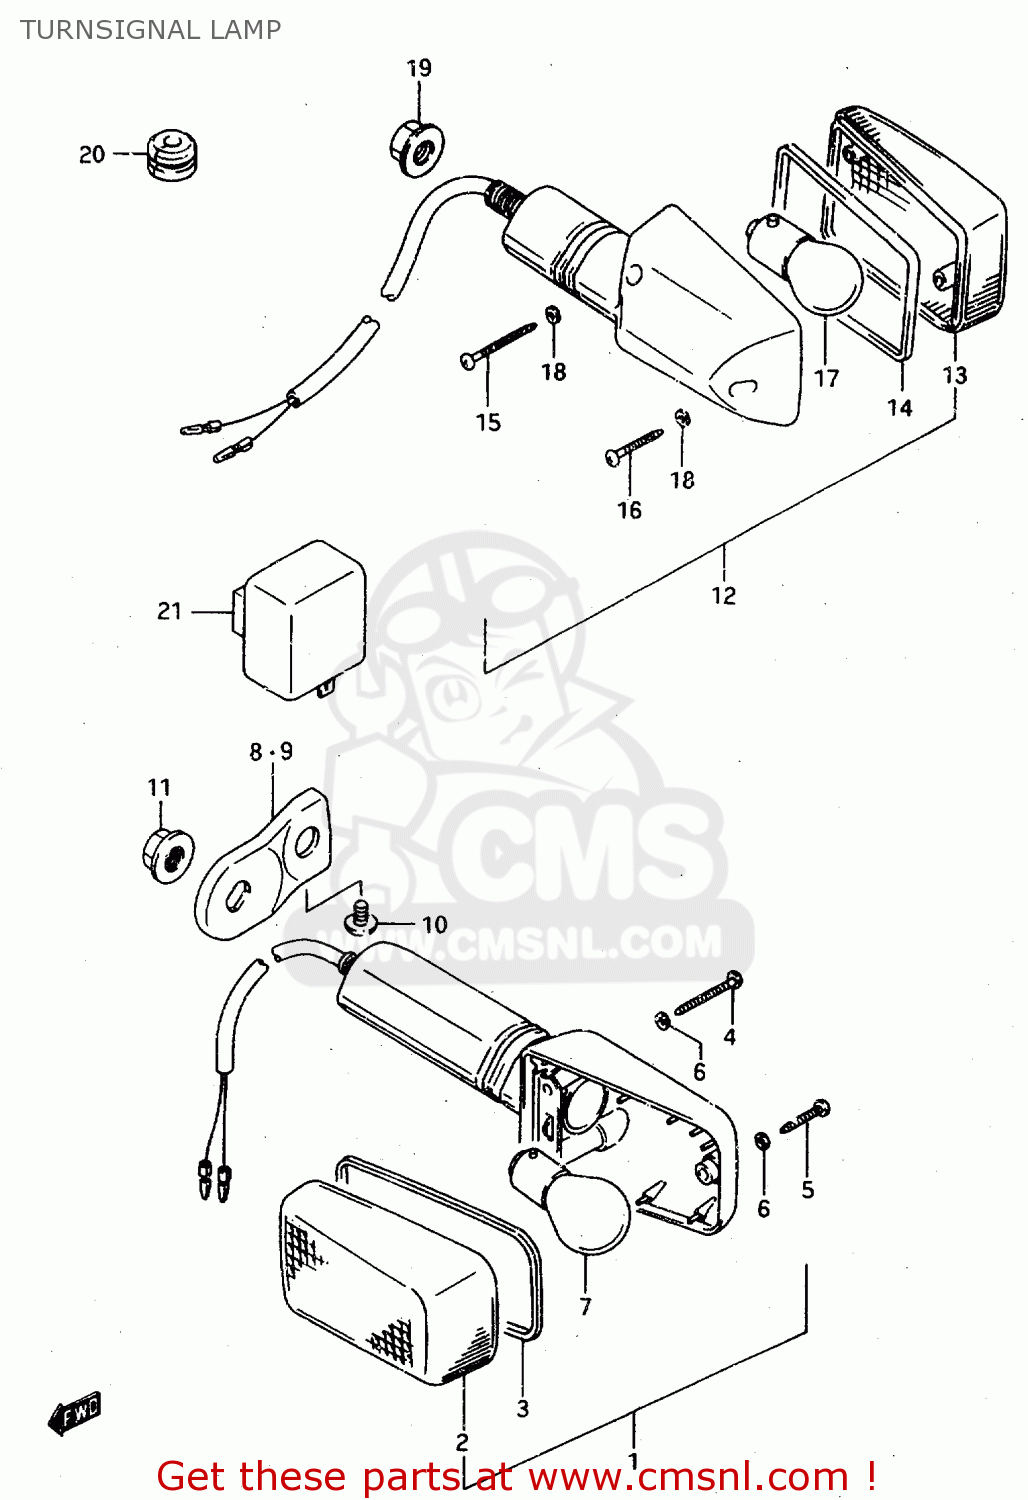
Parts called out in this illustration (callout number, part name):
1	LAMP ASSY,FR TURN SIGNAL
2	LENS
3	GASKET (NAS)
4	SCREW(3X30)
5	SCREW
6	GASKET (NAS)
7	BULB(12V21W)
8	BRACKET,FR TURN,R
9	BRACKET,FR TURN,L
10	SCREW
11	NUT
12	LAMP ASSY, REAR TURNSIGNAL
13	LENS
14	GASKET (NAS)
15	SCREW(3X30)
16	SCREW
17	BULB(12V21W)
18	GASKET (NAS)
19	NUT
20	GROMMET
21	RELAY ASSEMBLY,TURN SIGNAL
